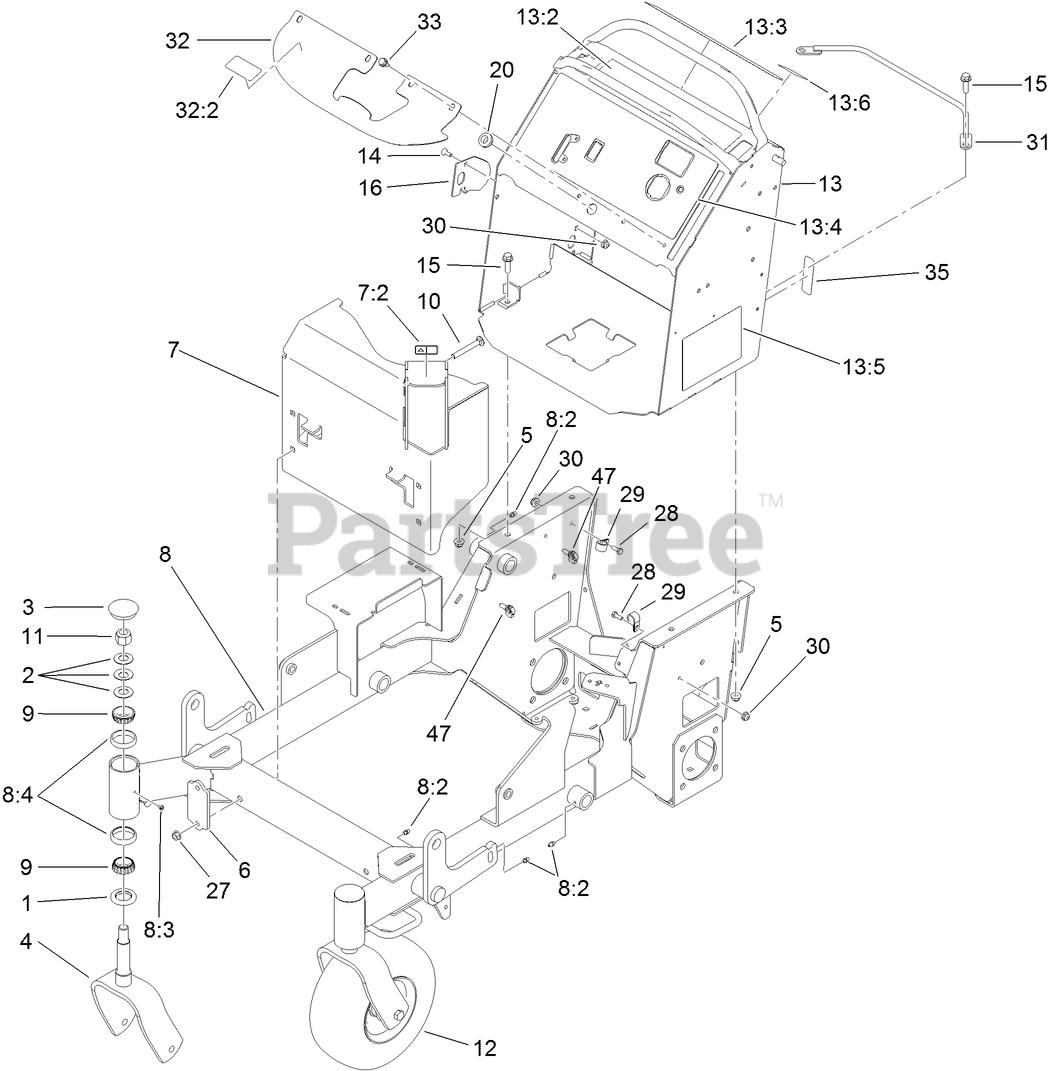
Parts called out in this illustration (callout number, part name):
1	SEAL-GREASE
2	WASHER-BELLVILLE
3	CAP-GREASE
4	FORK-CASTER
5	NUT-HF, NI
6	BRACKET-MOUNTING, GUARD
7	MUFFLER GUARD ASM
7:2	DECAL-WARNING
8	FRAME ASM
8:2	FITTING-GREASE
8:4	CUP-BEARING
9	BEARING-ROLLER, TAPERED
10	SCREW-CARR
11	NUT-LOCK, NI
12	WHEEL/TIRE AND BEARING ASM
13	CONTROL TOWER ASM
13:2	DECAL-OPC
13:3	DECAL-WARNING
13:4	DECAL-PANEL, CONTROL
13:5	DECAL-SERVICE AID
13:6	DECAL-STABILITY, CE
14	BOLT-CARR
15	SCREW-HHF
16	PLATE-STRIKER
20	GROMMET
27	NUT-HF
28	SCREW-HH
29	CLAMP-CABLE
30	NUT-HF
31	RETAINER-CABLE
32	COVER-TANK
32:2	DECAL-FILL, FUEL
33	SCREW-HWHTF
35	DECAL-FUSE
47	CLIP-HARNESS
